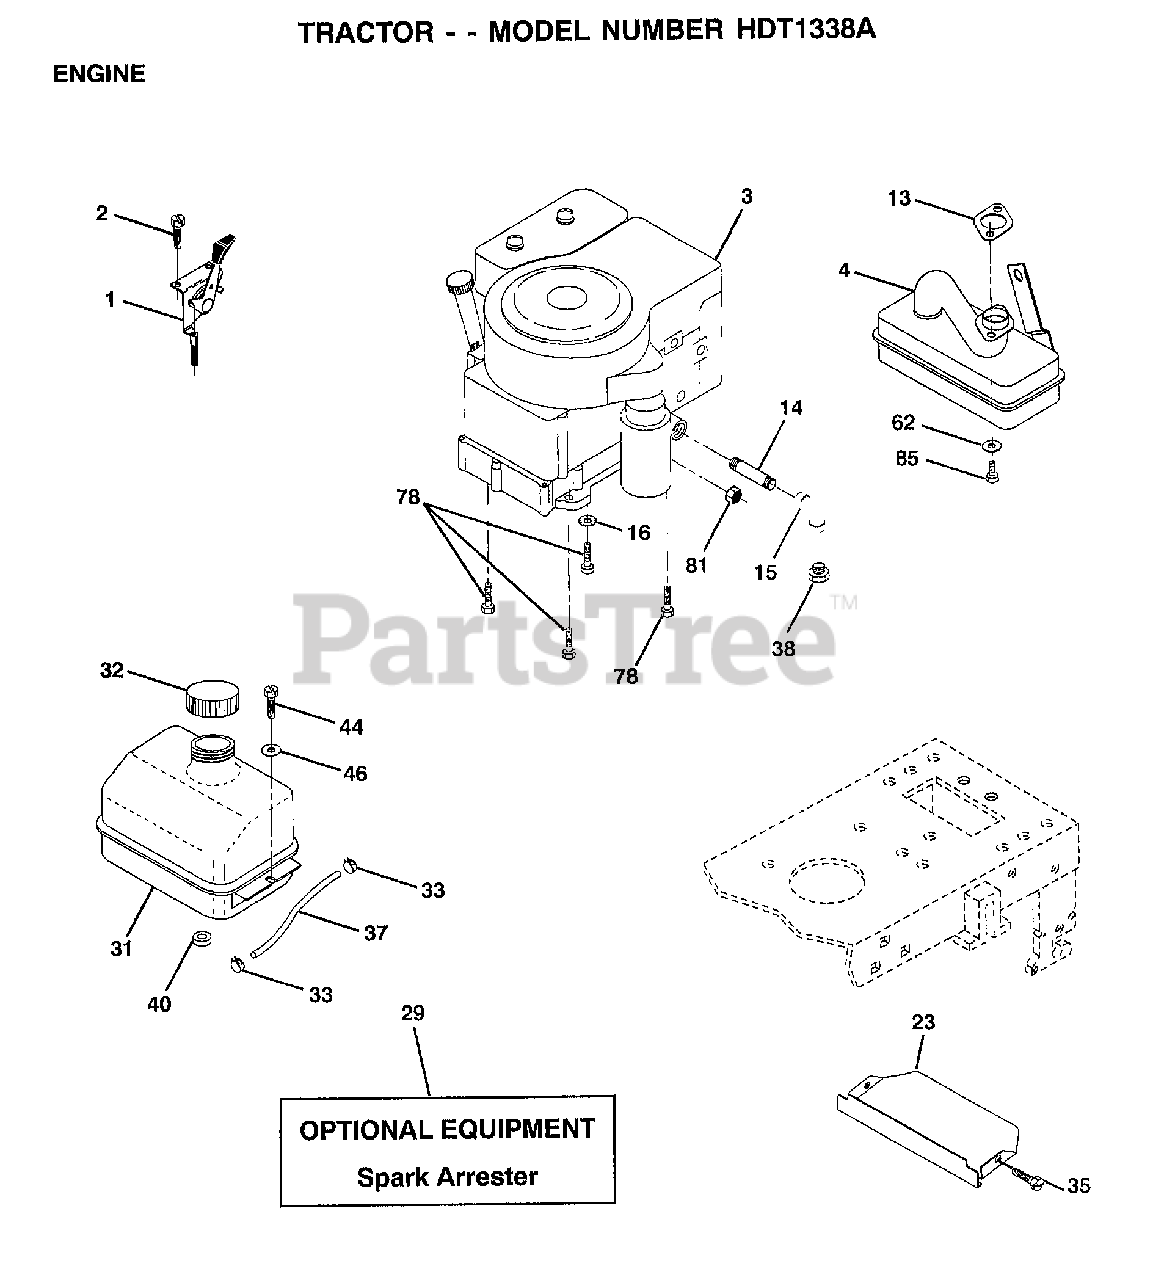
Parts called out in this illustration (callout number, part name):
1	CONTROL-THROT/CHO
2	SCREW LT
4	MUFFLER TEC. 13HP
14	PIPE NIPPLE LT
15	ELBOW
16	LOCKWASHER
23	SHIELD.BRN/DBR.GD
31	TANK.FUEL.LT.
32	CAP ASM FUEL
33	HOSE CLAMP
35	SCREW
37	LINE FUEL
44	SCREW HEX CRT
46	WASHER
62	LOCKWASHER
78	SCREW
81	NUT
85	SCREW HEX HD CAP
